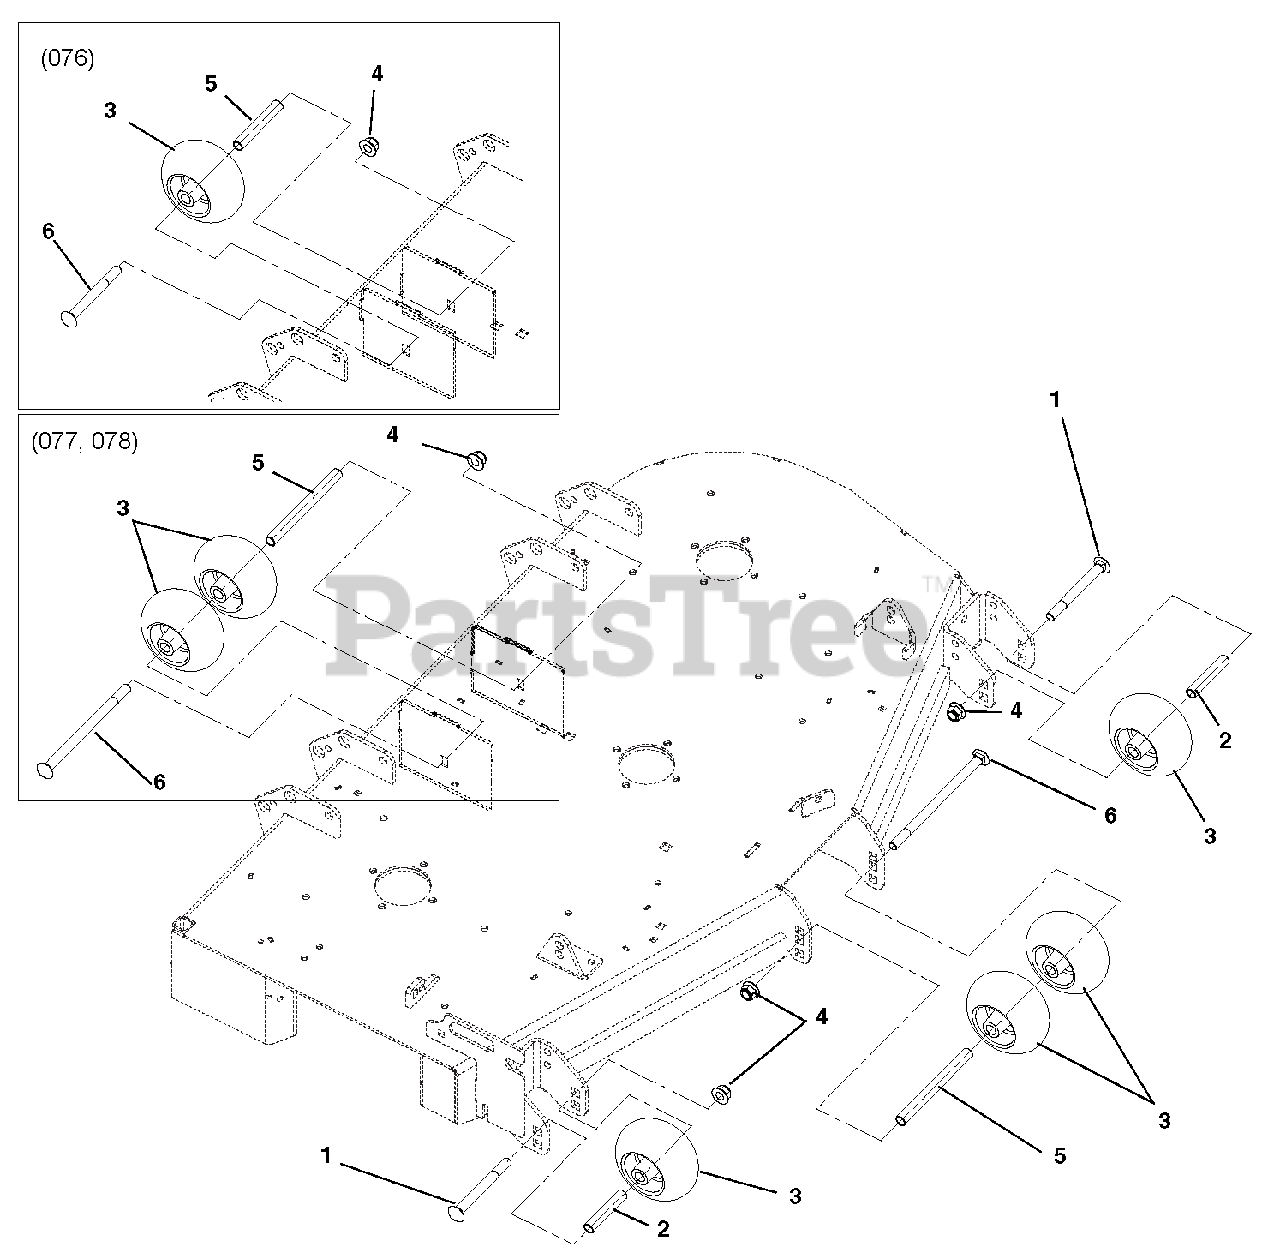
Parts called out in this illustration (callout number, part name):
1	BLT-RDHDSQNK .50-13X5.00 GR5YZ
2	SPACER, .510X.625X3.35
3	ANTI-SCALP WHEEL - 5X3 CTR
4	@NUT-LK-NYL-FLG .50-13 YWZC
5	SPACER, .510X.625X6.50
6	@BLT-RDHDSQNK .50-13X8.50 G5YZ
